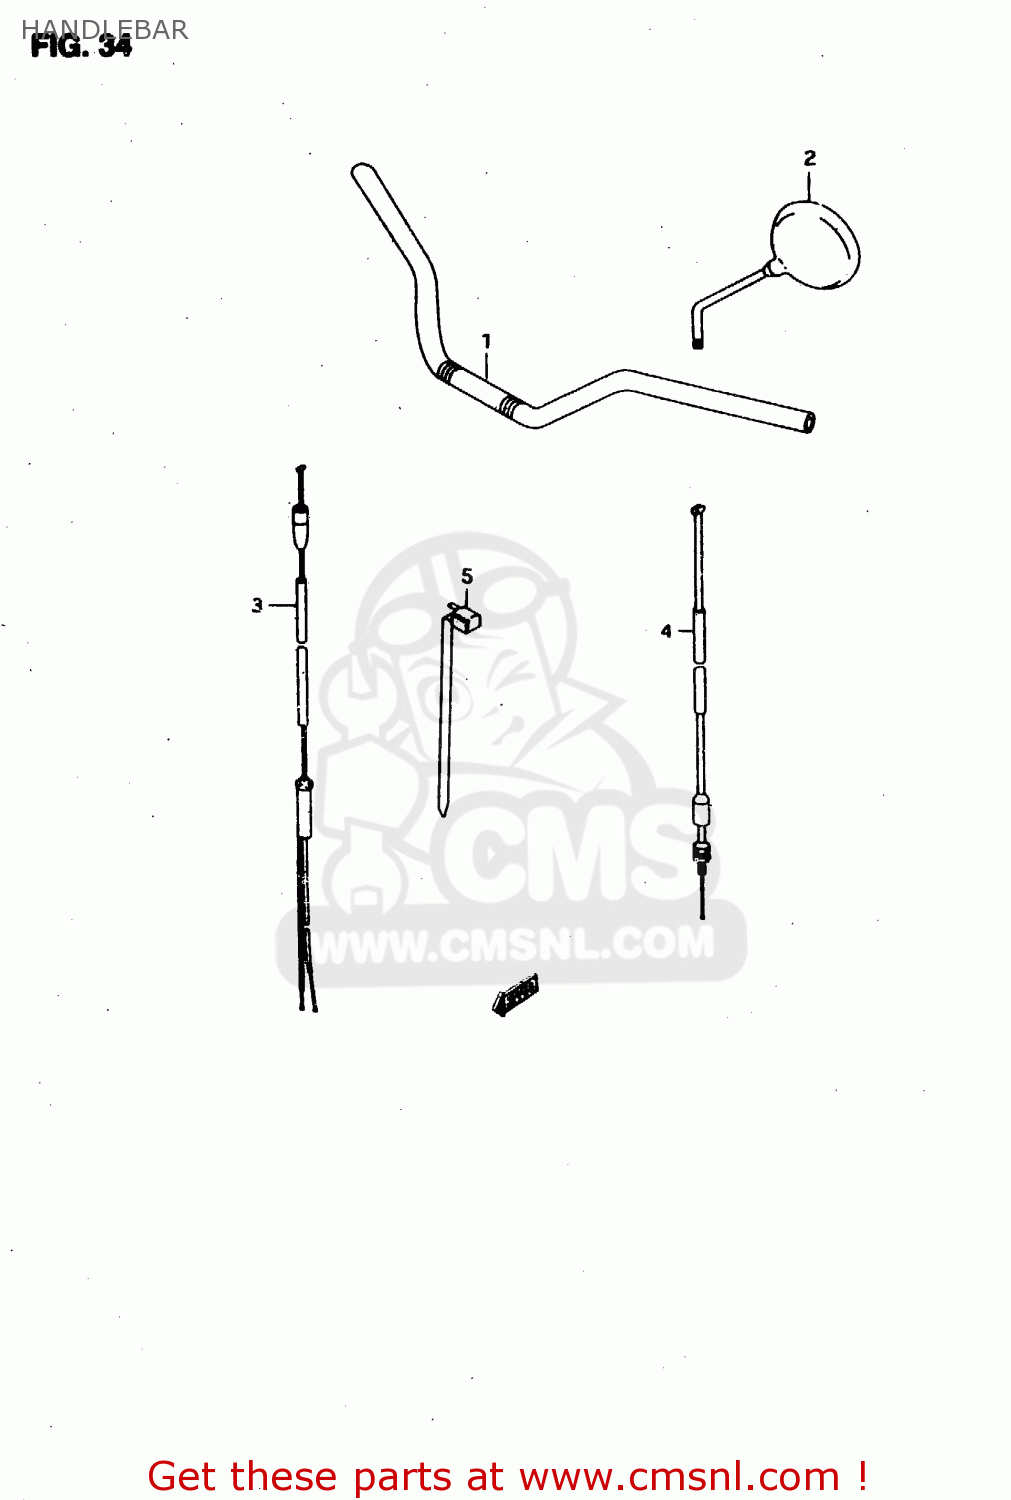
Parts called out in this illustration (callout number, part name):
1	HANDLEBAR
2	MIRROR ASSY
3	THROTLLE CABLE
4	CLUTCHCABLE
5	CLAMP(L:125)
